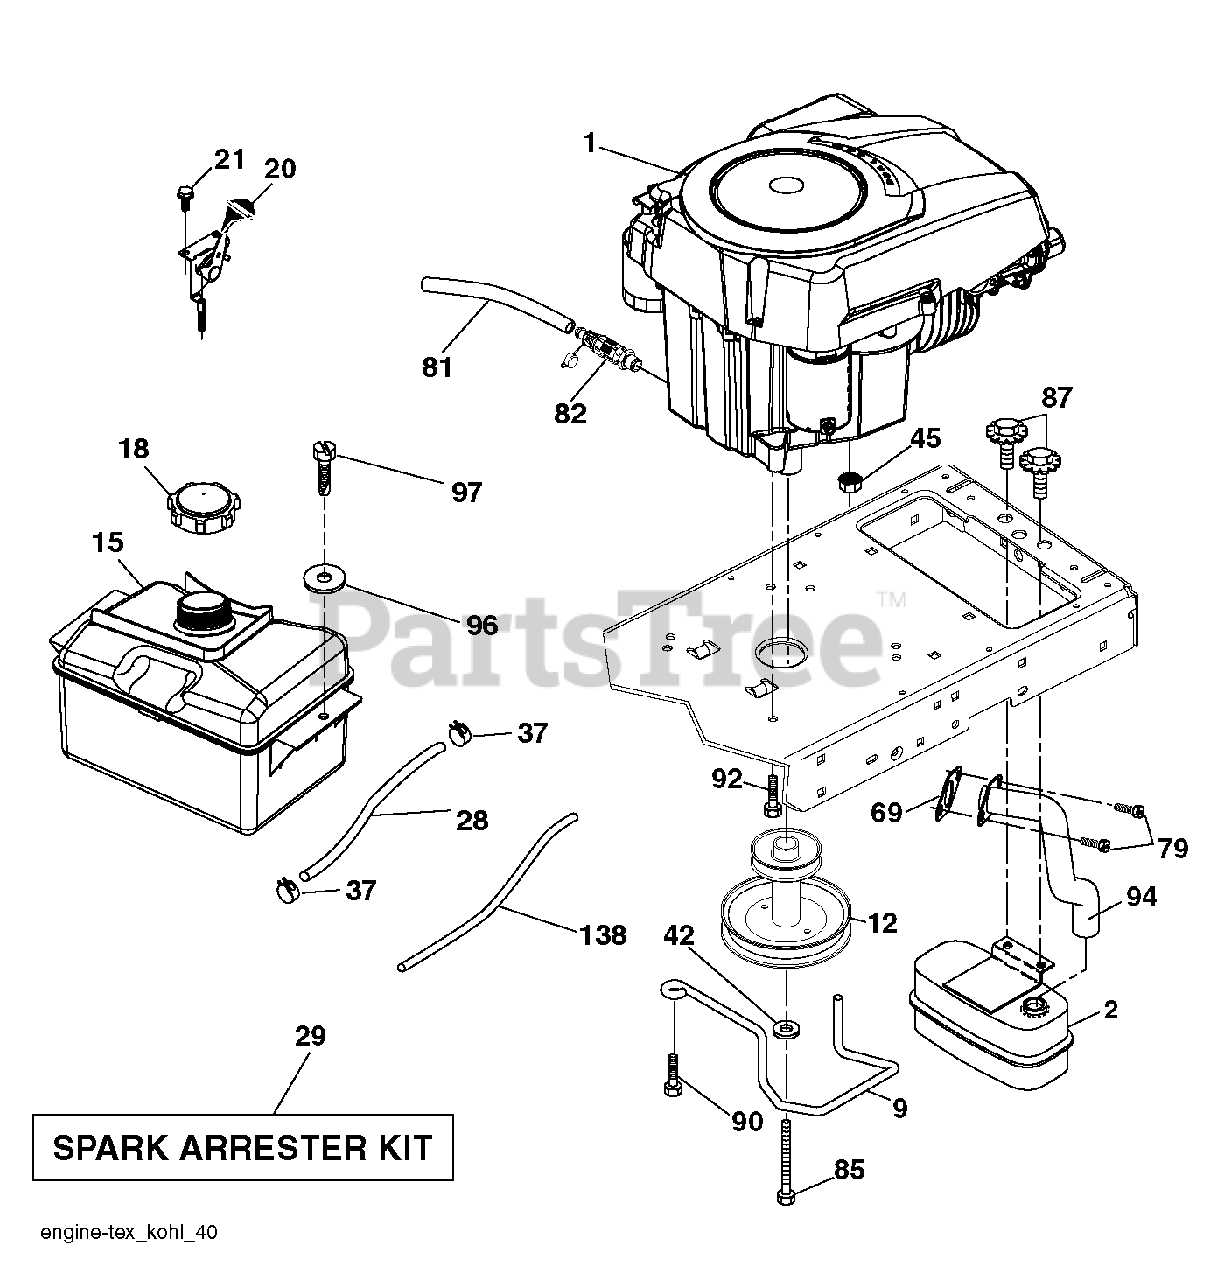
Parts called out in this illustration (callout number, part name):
2	MUFFLER.ASM.SNGL.XTNDED.DFLCTR
9	KEEPER.BELT.ENGINE
12	PULLEY.ENGINE.5.0.PD
15	TANK.ASM.FRT.2.5 GAL.W/CAP.EPA
18	CAP.FUEL.2 WAY VENT
21	SCREW.#10 X 0.750.BOS (2 2)
28	LINE.FUEL.20"FRONT.EMI
29	KIT.SPARK ARRESTOR(392390 B&S)
37	HOSE CLAMP
42	LOCKWASHER
45	NUT
69	GASKET.EXHAUST.KOHLER
79	SCREW.SOCKET HD.5/16-1
81	TUBE, DRAIN OIL ASM.
82	VALUE.OIL.DRAIN
85	BOLT HEX 7/16-20X4-1/4"
87	BOLT, 5/16-18 X 1 3/4
90	SCREW 3/8-16X1
92	SCREW 3/8-16X1
94	Exhaust Tube, Kohler Courage
97	SCREW HEXWSHR 1/4-20X3/4
138	RP PURGE LINE
